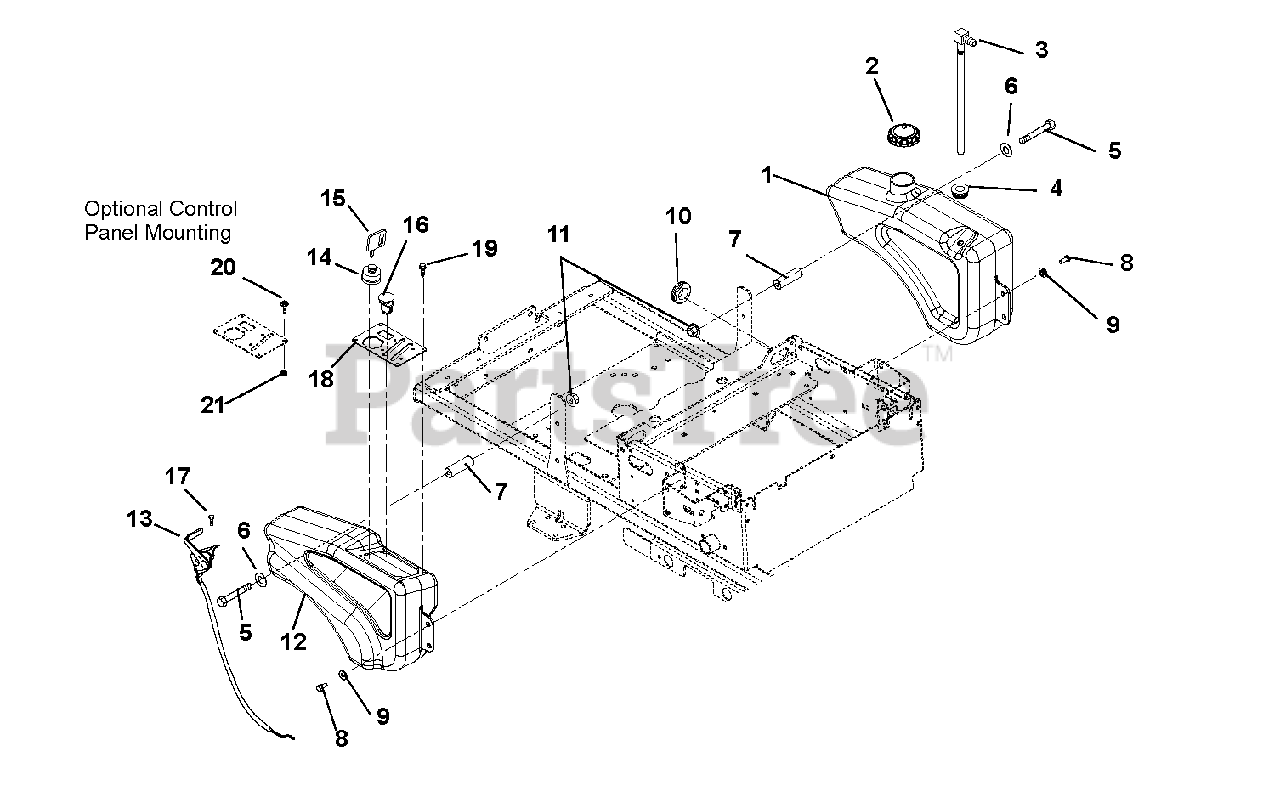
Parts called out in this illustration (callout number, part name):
1	Gas Tank
2	Fuel Cap
3	Fitting, Tank
4	Bushing, Flange .375 x 1.062 x .625
5	Bolt, Hex .31-18 x 3.50 Grade 5
6	Washer, Flat Steel .38 x .875 x .083
7	Spacer, Tank Mount
8	Screw, Tapping .31-18 x .75 Hex Washer Head
9	Shoulder Spacer
10	Grommet .125 x 1.000 ID
11	Nut, .31-18 Nyloc Flange
13	Choke Cable, Throttle 40"
14	Key Switch
15	Key, with Cap
16	Switch, Clutch
17	Screw, Tapping 10-24 x .50 Hex Washer Head
18	Control Panel
19	Rivet, Plastic .195 Diameter
20	Bolt, Round Head Square Neck .38-16 x 2.50 Grade 5
21	Nut, Locking Nylon 10-24 with Insert
